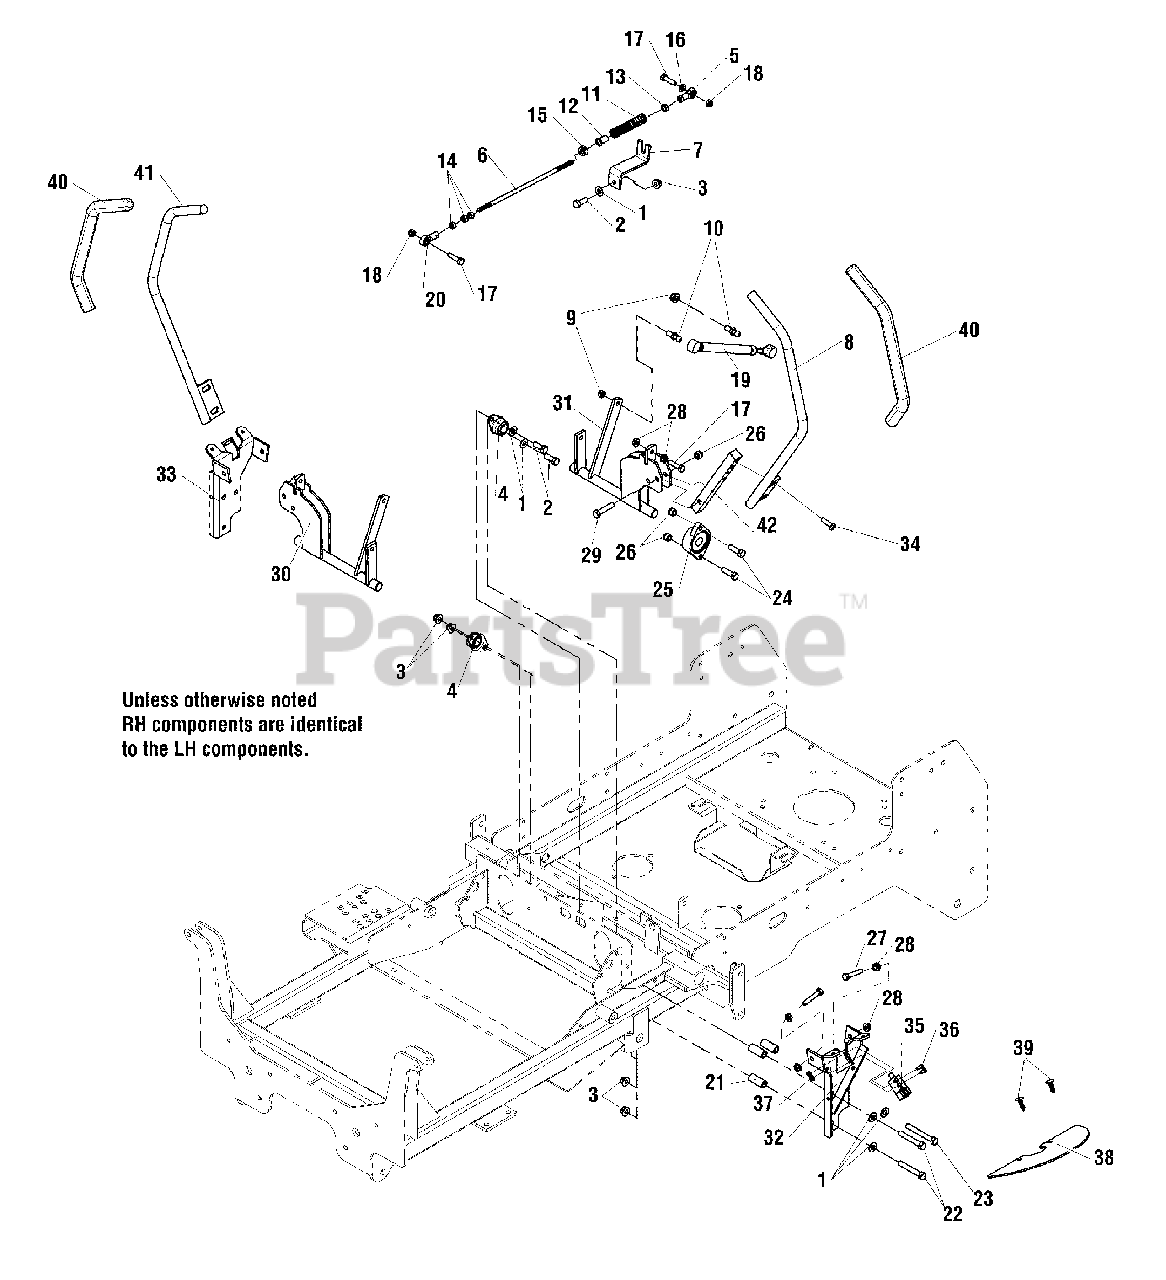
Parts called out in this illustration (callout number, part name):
1	WASHER, 3/8 SAE
2	BOLT, 3/8-16 X 1" GD5
3	NUT, 3/8-16 HEX NYLOCK FLANGE
4	BEARING, BRONZE FLANGE 3/4"
5	BALL JOINT 5/16-24 LH FEMALE BRONZE RACE
6	ROD, HYDRO LINKAGE
7	MOUNT, REVERSE RETURN - BLK
8	WELD, HANDLE MOTION CONTROL-LH - BLK
9	NUT, 5/16-18 HEX NYLON FLANGE
10	10MM BALL STUD, 5/16-18 X 3/4
11	SPRING, COMPRESSION
12	BUSHING, FLANGE 3/8ID X 7/8 LONG
13	NUT, 5/16 HEX LH
14	NUT, HEX 5/16-24
15	SET COLLAR, 5/16"
16	WASHER, 5/16" SAE
17	BOLT, 5/16-18 X 1-1/4" GD5
18	NUT 5/16-18 HEX NYLON LOCK
19	DAMPENER, CONTROL
20	BALL JOINT 5/16-24 RH FEMALE BRONZE RACE
21	SPACER, .63 X .39 X 1.50
22	BOLT, 3/8-16 X 2-1/2" GD5
23	BOLT, 3/8-16 X 3" GD5
24	BOLT, 3/8-16 X 1-1/4" GD5
25	BEARING, FLANGE
26	NUT, 3/8-16 HEX NYLON LOCK
27	BOLT, 5/16-18 X 1-3/4" GD5
28	NUT, 5/16-18 HEX SM. SERR. FLG.
29	BOLT, 3/8-16 X 1-3/4" GD5
30	WELD, CONTROL SHAFT, RH - BLK
31	WELD, CONTROL SHAFT, LH - BLK
32	WELD, NEUTRAL LOCK, LH - BLK
33	WELD, NEUTRAL LOCK, RH - BLK
34	SCREW-HEX WZ LOCK FLNG 5/16-18X0.750BLK
35	SWITCH, PLUNGER, N.O./N.C.
36	10-24 X .5 SCREW
37	NUT, HEX, #10-24
38	GUARD, RUBBER MOTION CONTROLS
39	PUSH RIVET (TREE TYPE) BLACK
40	GRIP, FOAM, 3/4" ID, 16" LONG
41	WELD, HANDLE MOTION CONTROL, RH - BLK
42	MOUNT, CONTROL ARM - BLK
